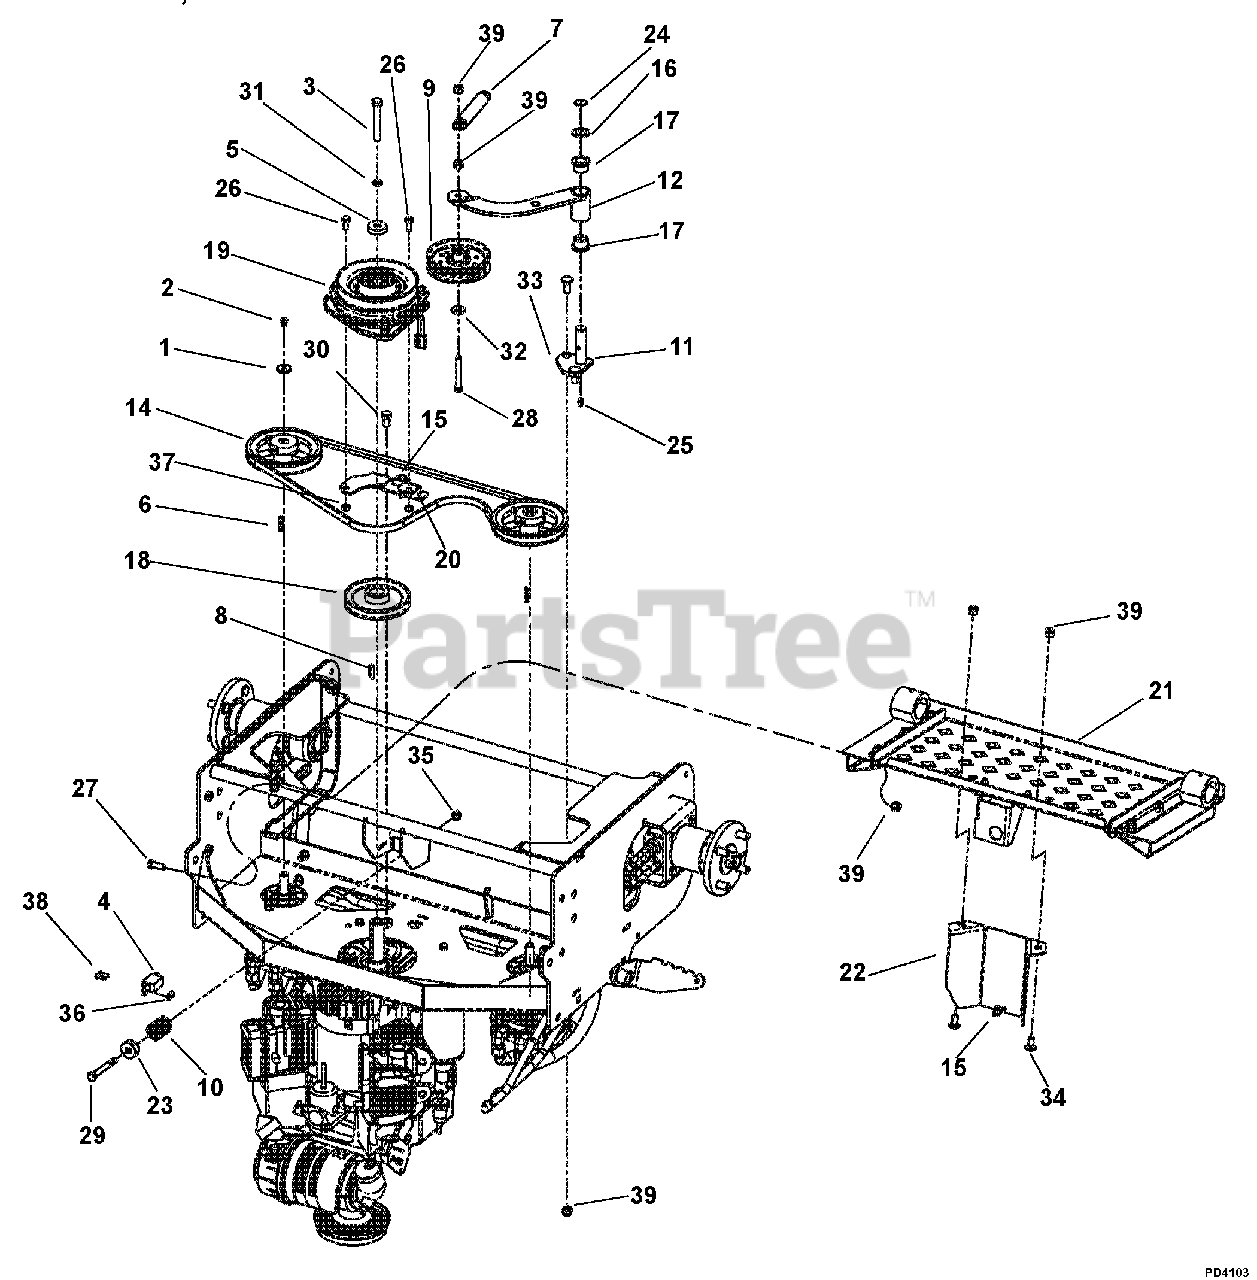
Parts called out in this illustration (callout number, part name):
1	Washer, Locking .250 x .077 Heavy
2	Bolt, M6 x 1.00 x 10 Hex 8.8
3	Bolt, Hex .44 x 3.00 Grade 5
4	Switch
5	Spacer, PTO Clutch
6	Key, Special M5 x 28
7	Spring, Idler
8	Key, .250 x .250 x .995 TPR
9	Idler
10	Spring
11	Idler Post
12	Idler Arm
13	V-Belt
14	Pulley, RH Pump, Set Screw Included
15	Tie Wrap, Black
16	Bushing, Machine .750 x 1.25 x .048
17	Bearing, Flange .750 x 1.00 x .750 Bracket
18	Pulley, V-Belt 4.78PD x 1.000
19	Clutch Assembly, Ogura
20	Plate, Clutch Dog
21	Assembly, Foot Plate
22	Cover, Operator Presence Control
23	Washer, Spring
24	Ring, Retaining, External .750 x .042
25	Grease Zerk, 1/4-28 Straight .69
26	Bolt, Hex .31-18 x .75 Grade 5
27	Bolt, Hex .31-16 x 1.00 Grade 5
28	Bolt, Hex .31-16 x 2.50 Grade 5
29	Bolt, Hex .31-16 x 3.25 Grade 5
30	Bolt, 7/16-14 x .750 Hex 5
31	Washer, Flat, Steel .38 x .875 x .083
32	Washer, Flat, Steel .438 x 1.00 x .083
33	Bolt, Round Head Square Neck .38-16 x 1.00 Grade 5
34	Bolt, Round Head Square Neck .38-16 x .75 Grade 5
35	Nut, Hex .31-16
36	Nut. Locking, Nylon 10-24 With Insert
37	Nut, Locking, Nylon .312-18
38	Screw, Machine 10-24 x .625 P/HD
39	Nut, Locking, Nylon .38-16
